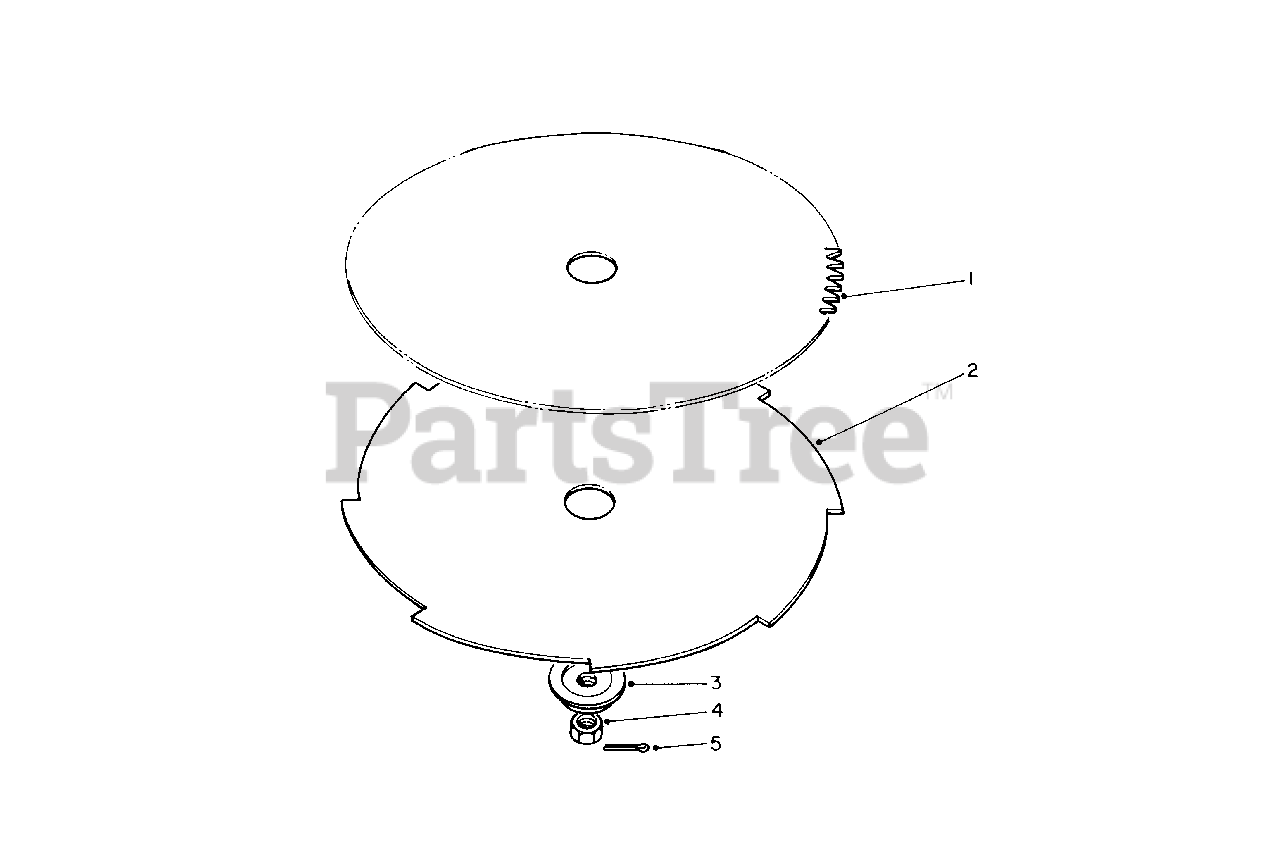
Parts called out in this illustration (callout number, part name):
1	8" Dia. Blade (80 Tooth)
2	8" Dia. Blade (8 Tooth)
3	Adapter-Blade
4	Nut L.H.
5	Pin Cotter
